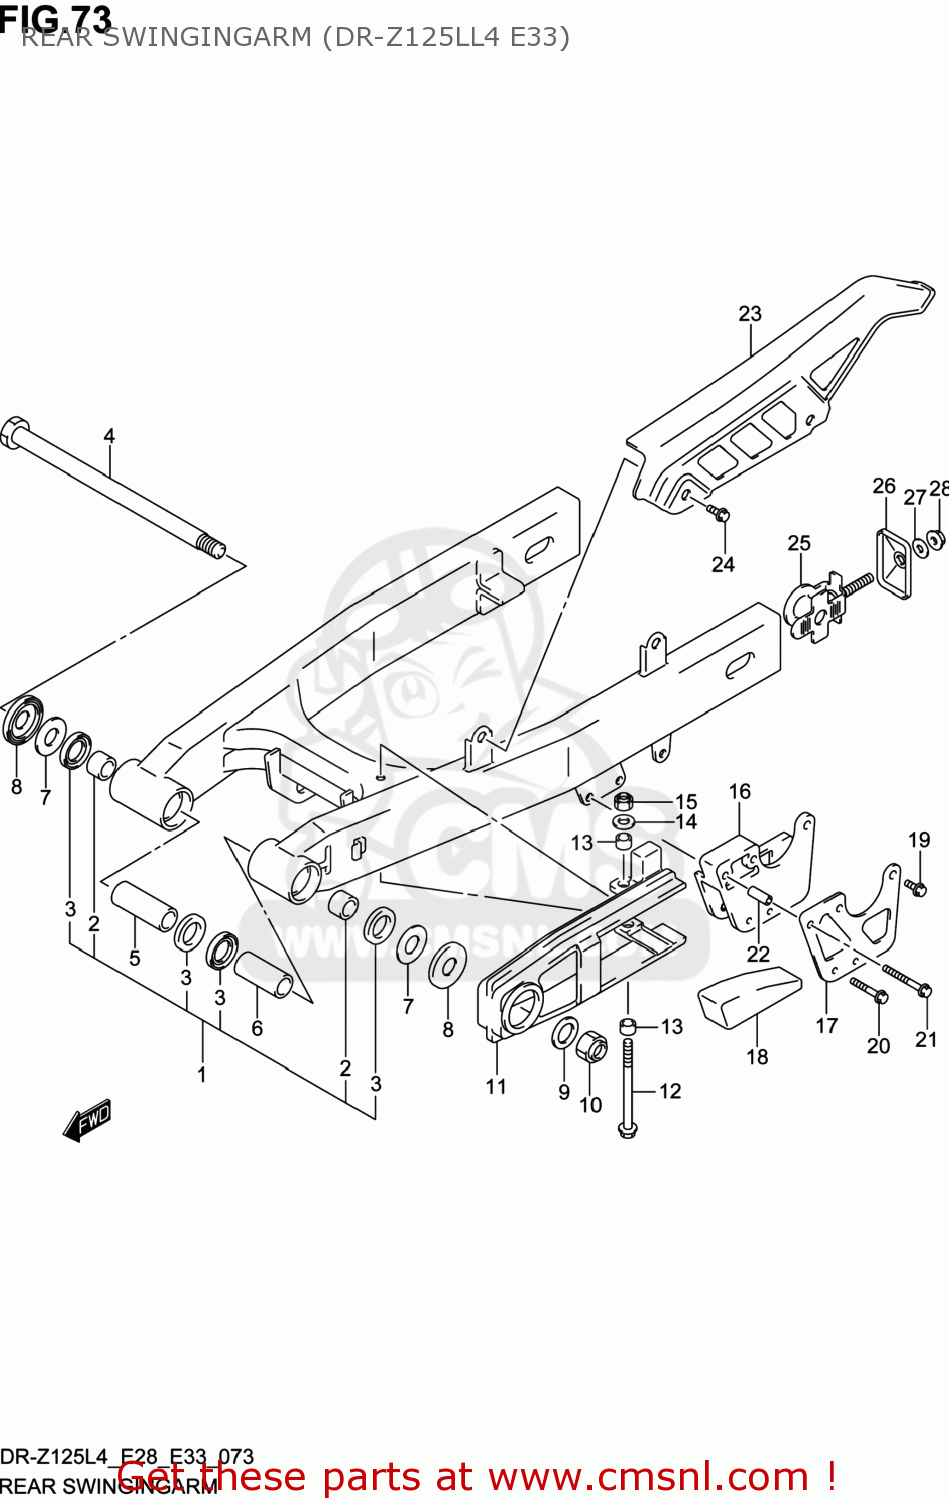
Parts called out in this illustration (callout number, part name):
1	SWINGINGARM ASSY,RR
2	BUSHING,RR SWGARM PIVOT
3	SEAL,OIL(20X27X5)
4	SHAFT,RR SWINGINGARM PIVOT
5	SPACER,RR SWGARM PIVOT,R
6	SPACER,RR SWGARM PVT
7	WASHER
8	COVER,RR SWGARM DUST SEAL
9	WASHER(14.5X24X2.3)
10	NUT
11	BUFFER,CHAIN TOUCH DEFENSE
12	BOLT
13	SPACER(6.5X9X6.5)
14	WASHER
15	NUT
16	GUIDE,CHAIN
17	PLATE,GUIDE CHAIN OUTER
18	DEFENSE,CHAIN GUIDE
19	BOLT(6X16)
20	BOLT(6X40)
21	BOLT(6X30)
22	SPACER(6.5X10X23.5)
23	CASE,CHAIN
24	BOLT(6X10)
25	ADJUSTER,CHAIN
26	PLATE,CHAIN ADJUSTER
27	WASHER(12.5X26X2.3)
28	NUT
